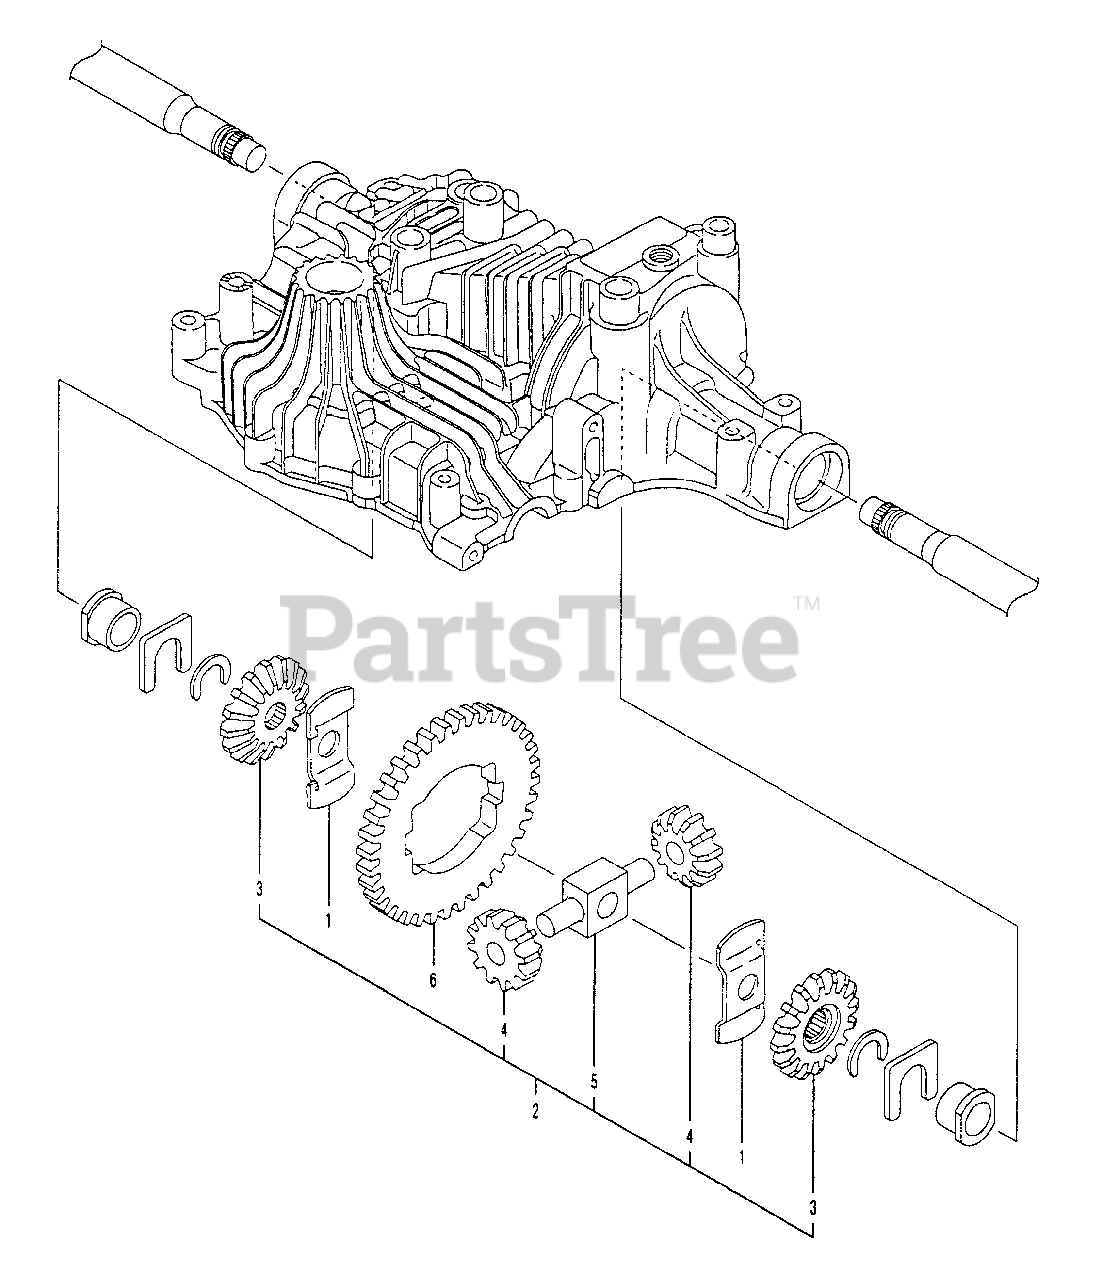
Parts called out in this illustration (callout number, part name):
1	THRUST WASHER (DIFF.
2	DIFF. GEAR KIT
3	DIFF. SIDE GEAR
4	DIFF. PINION
5	SHAFT (DIFF. PINION
6	FINAL GEAR 55
